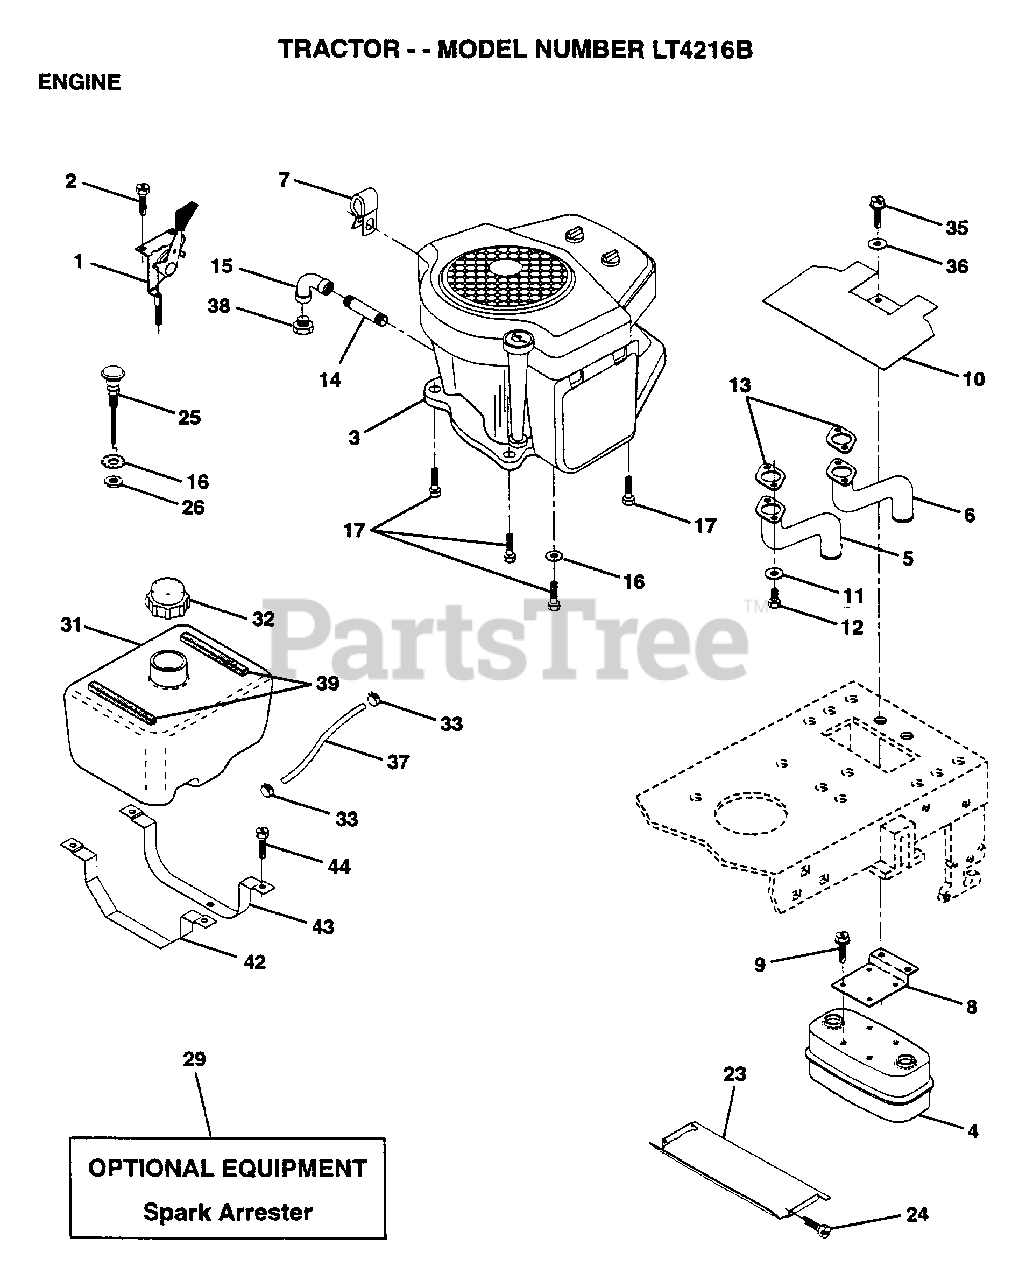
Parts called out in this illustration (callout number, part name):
1	CONTROL.THT.FLG.
2	SCREW LT
3	ENGINE, B&S
5	EXHAUST.B&S.18.LH
6	EXHAUST.B&S.18.RH
7	CLAMP.TUBE.DBL.EN
8	BRACKET MUFFLER
9	SCREW ST
10	SHIELD.HEAT.
14	PIPE NIPPLE LT
15	ELBOW
16	LOCKWASHER
17	SCREW LT
23	HEAT SHIELD
24	SCREW
25	CONTROL.CHK.26.38
31	TANK FUEL 1.9 NAT
32	CAP ASM FUEL
33	HOSE CLAMP
35	SCREW
36	WASHER
37	FUEL LINE T
39	"STRIP,FORM"
42	STRAP TANK FUEL
43	STRAP TANK FRONT
44	SCREW
